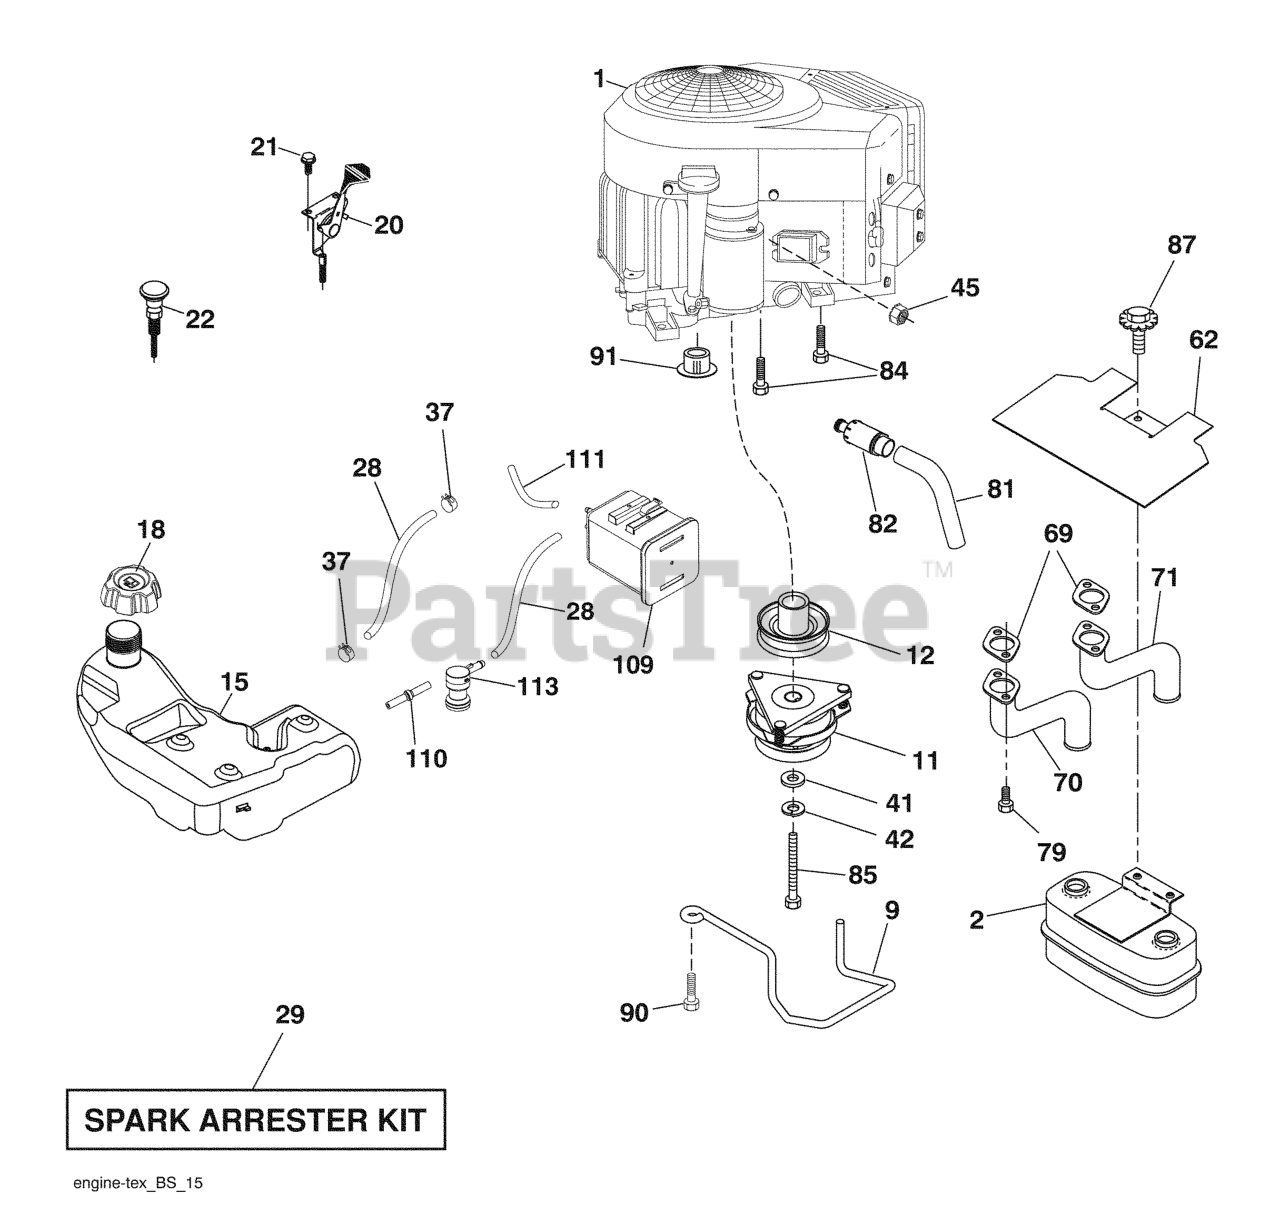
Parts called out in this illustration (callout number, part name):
2	MUFFLER.TWIN.CYL.LOW.TONE
9	KEEPER.BELT.ENGINE.4.2
11	CLUTCH MZ ZTR GT.48/54"1.125"
12	PULLEY ENGINE
15	RP_TANK.ASM.4.GAL.CARB.1.PORT.
18	CAP ASM
20	THROTTLE CABLE
21	SCREW.#10 X 0.750.BOS
22	CONTROL.CHOKE.ERGO.PUSH-IN.BLA
28	LINE.FUEL.64"REAR.EMIS
29	KIT.SPARK ARRESTOR 794945 B&S
37	HOSE CLAMP
42	LOCKWASHER
45	NUT
62	RP SHIELD HEAT MUFFLER
69	GASKET.MUFFLER
70	RP.EXHAUST.TUBE.LH.BS/TWIN
71	EXHAUST.TUBE.RH.BS/TWIN
79	SCREW.SOCKET.HEAD.5/16-18
81	TUBE, DRAIN OIL ASM.
82	PLUG DRAIN OIL EASY
84	SCREW.3/8-16
85	BOLT HEX 7/16-20 X 3.75 GR. 5
87	BOLT.5/16-18UNCX1.W/SEMS.BLK
90	SCREW 3/8-16X1
91	BUSHING.1.375OD
109	CANNISTER, CARBON
110	VALVE.ASM.ANTI-SLOSH
111	RP PURGE LINE
113	VALVE.SLANT.CARTRDG.90 DEG.TEX
